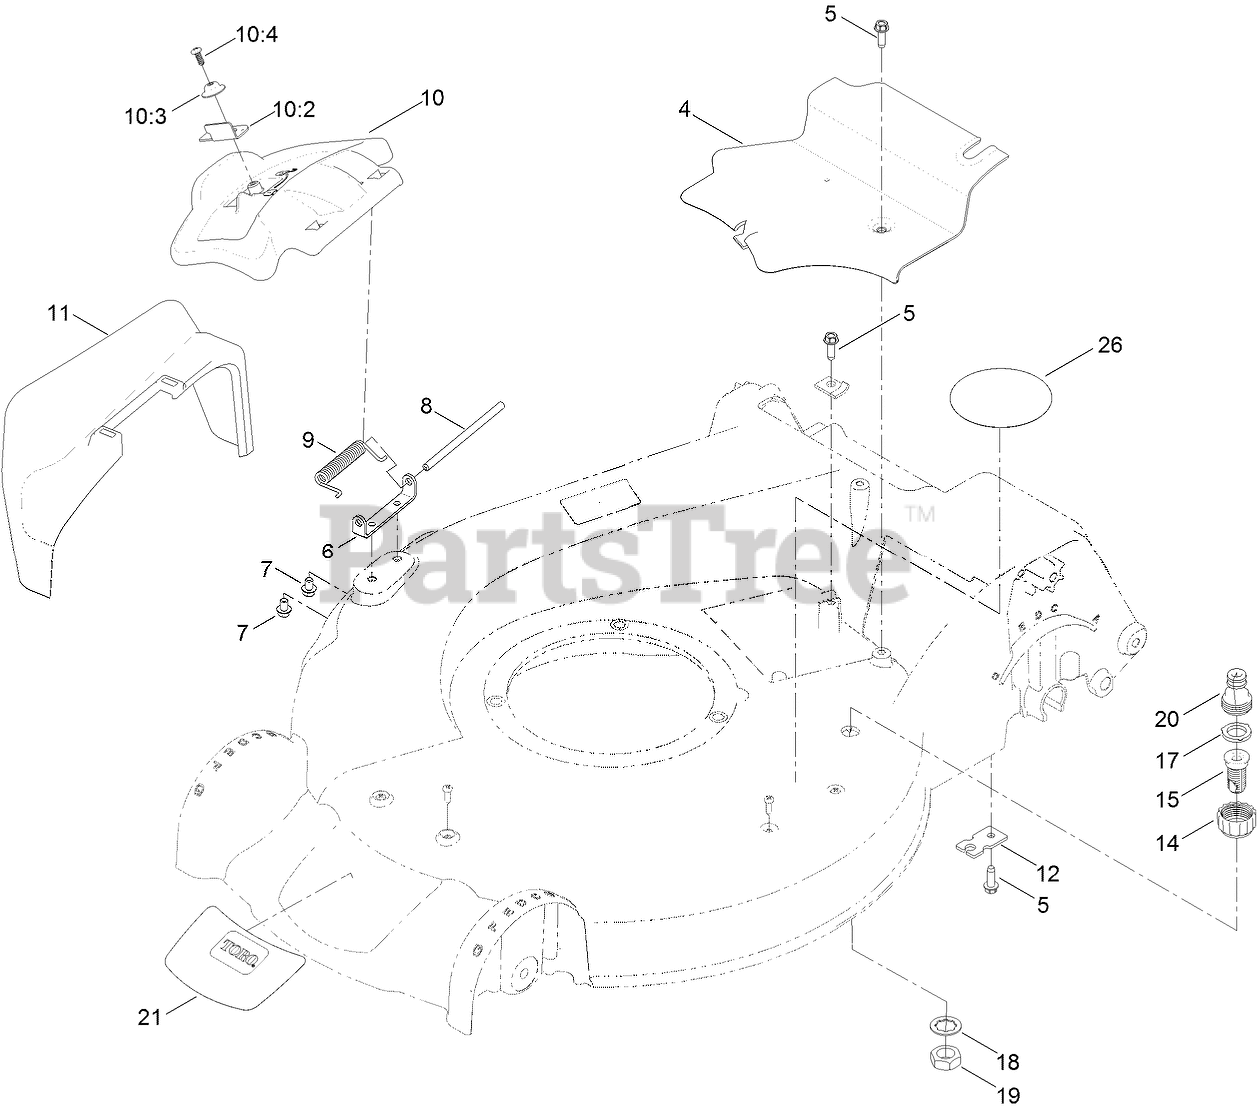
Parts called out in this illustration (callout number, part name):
4	COVER-BELT
5	SCREW-HWHTF
6	BRACKET-COVER
7	SCREW-HWH
8	ROD-COVER
9	SPRING-TORSION
10	DISCHARGE DOOR ASM
10:2	LATCH-DOOR
10:3	CAP-DOOR
10:4	SCREW-PLASTITE
11	CHUTE-DISCHARGE, SIDE
12	BRACKET-CABLE, TRACTION
14	COUPLING-HOSE, WASHOUT PORT
15	PORT-WASHOUT
17	WASHER-SEAL, WASHOUT PORT
18	WASHER-TOOTH, INTERNAL
19	NUT-JAM
20	ADAPTER-CONNECT, QUICK
21	DECAL-DECK
26	DECAL-POS
